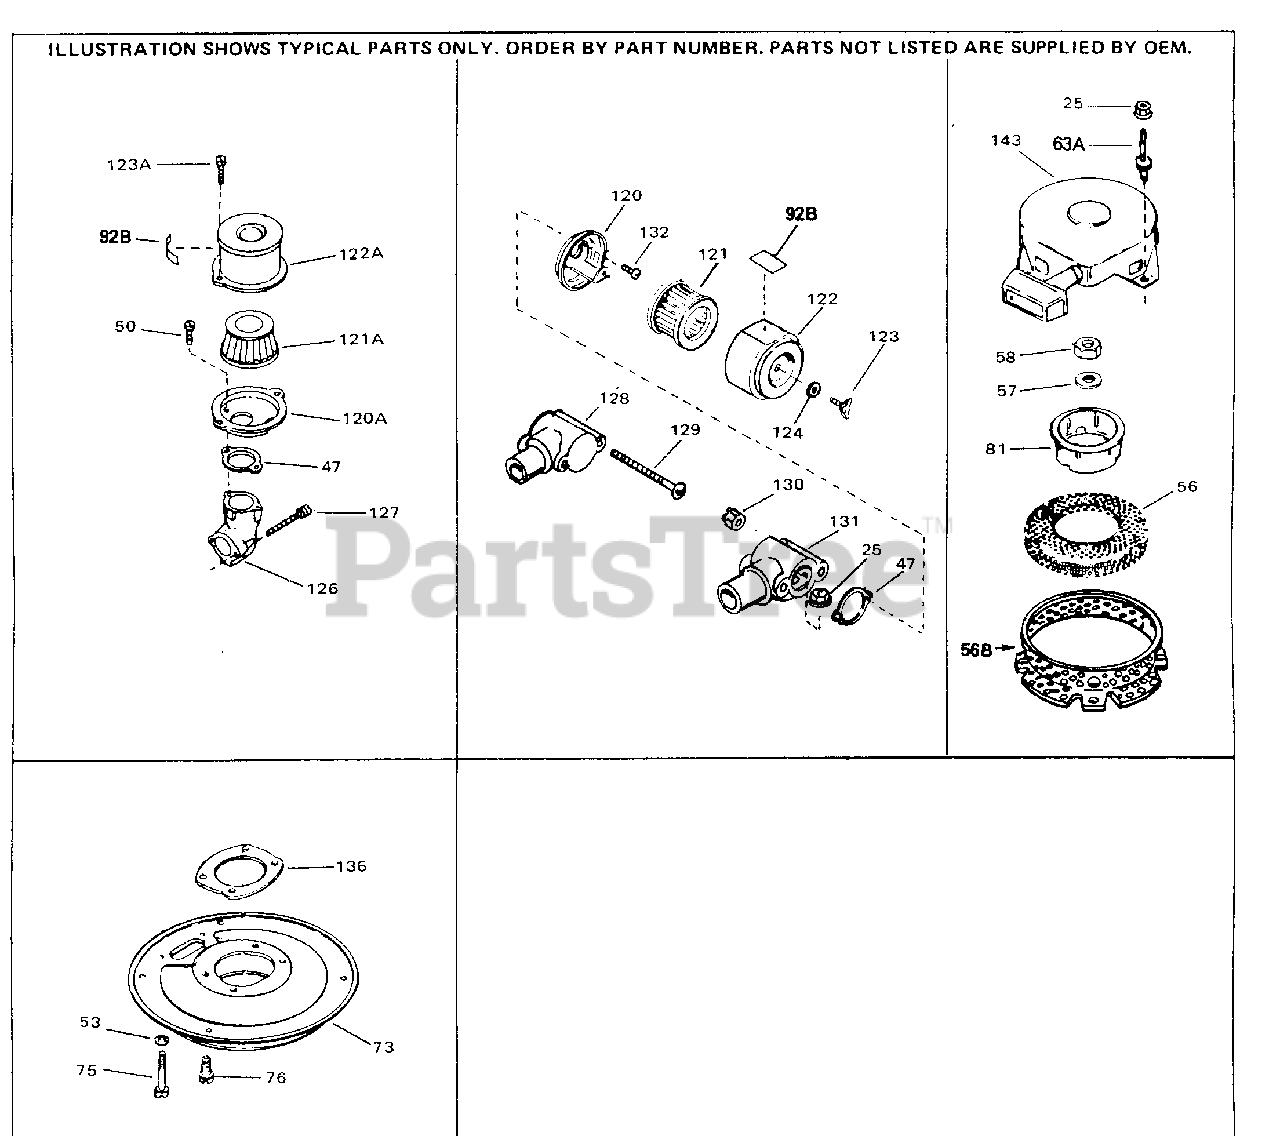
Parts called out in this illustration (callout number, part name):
25	Nut, Hex, 1/4-20 (Use as required)
25	Nut, Hex, 1/4-28 (Use as required)
47	Gasket
50	Screw, Torx T-25, 10-32 x 5/8"
56	Screen, Starter cup
58	Nut, Flywheel
63A	Pop Rivet (Can be purchased locally)
73	Muffler (Incl. 73A, 75 & 82A)
75	Screw, 1/4-20 x 1-7/8"
76	Screw, 5/16-18 x 5/8"
81	Cup, Starter
120	Base Assy., Filter
121	Air Filter
122	Cover, Air filter
123	Screw, 10-24 x 1/2"
136	Gasket, Flange
143	Starter, Rewind Refer to Division 5, Section C, page 25 for breakdown
